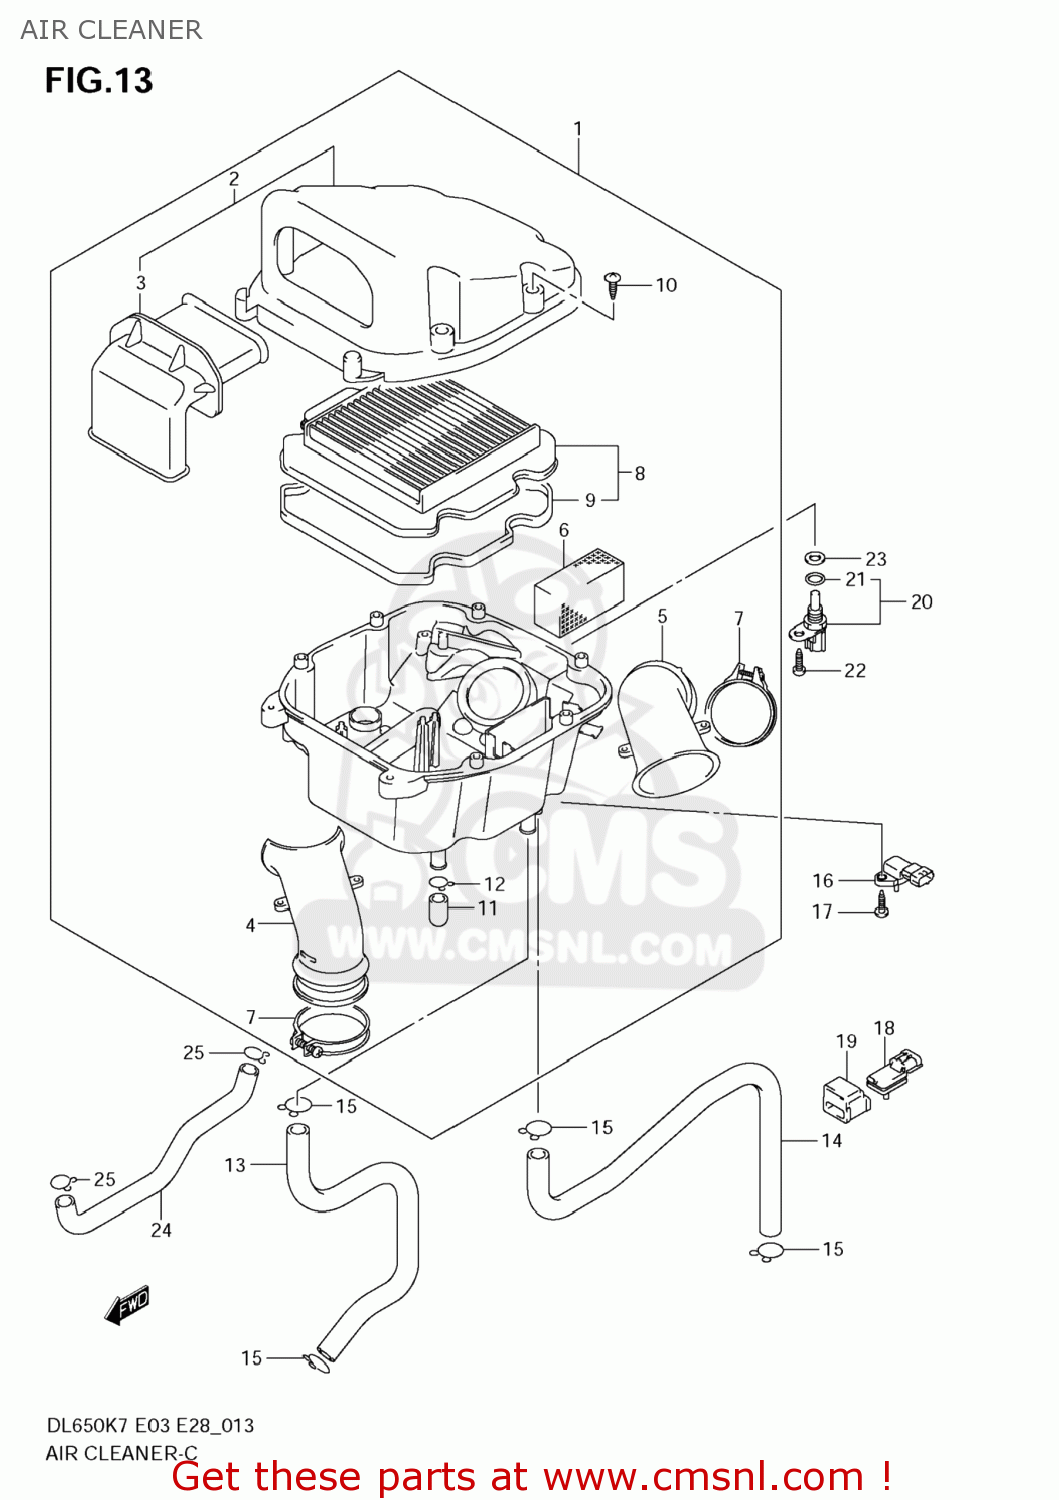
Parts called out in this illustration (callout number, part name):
1	CLEANER ASSY,AIR
2	CAP,AIR CLEANER
3	TUBE,INLET
4	TUBE,OUTLET
5	TUBE,OUTLET
6	FILTER,BREATHER
7	CLAMP
8	FILTER ASSY
9	GASKET,AIR CLEANER (NAS)
10	SCREW
11	PLUG
12	CLIP
13	TUBE,BREATHER CYLINDER
14	TUBE,BREATHER CRANKCASE
15	CLIP
16	SENSOR,BOOST
17	SCREW
18	SENSOR,PRESSURE
19	HOLDER,SENSOR
20	SENSOR,AIR TEMP
21	O RING
22	SCREW
23	GASKET(12X17X1) (NAS)
24	HOSE,ISC CLNR
25	CLIP
